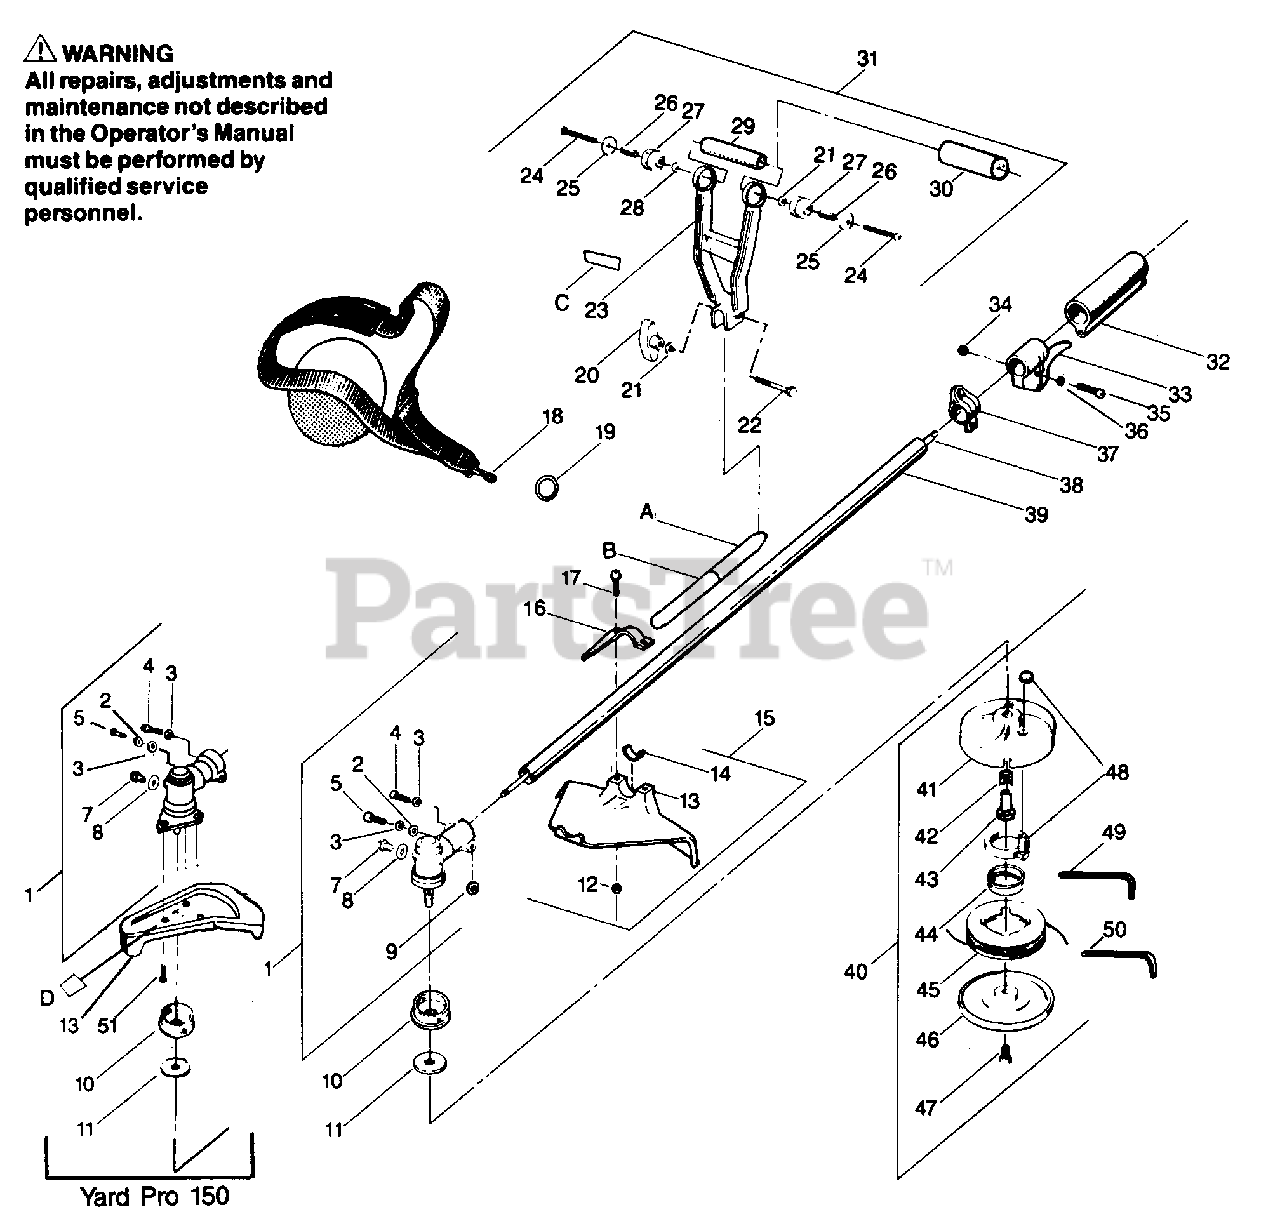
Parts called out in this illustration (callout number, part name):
2	Washer - 5mm - Flat - Gear Box - Index/Pinch Clamp
3	Lockwasher - 5mm - Gear Box - Index/Pinch Clamp
4	Screw - 5 x 12.5mm - Soc. Hd. - Gear Box - Index
5	Screw - 5 x 25mm - Soc. Hd. - Gear Box - Pinch Clamp
9	Washer - Spacer - Gear Box - Pinch Clamp - PRO150
10	Adaptor - Upper
11	Adaptor - Lower
12	Nut - 5mm - Shield - PRO150 Only
14	Spacer - Shield - PRO150 Only
15	Shield Ass'y.(incl.#12, 13, 14, 16 & 17) PRO150 Only
16	Bracket Shield - PRO150 Only
17	Screw - 5 x 25mm - Shield PRO150 Only
18	Shoulder Strap
19	Key Ring - Shoulder Strap
20	Knob - Handle
21	Washer - Handle
22	Screw - Handle - #1/4 - 20 x 1-3/4"
23	Handle Antivibe
24	Screw - #12 - 11 x 2" - Isolator Handle
25	Cup - Isolator - Handle
26	Spacer - Isolator Handle
27	Isolator - Handle
29	Center - Section - Handle
30	Cushion - Handle
31	Ass'y. - Antivibe Handle (Inc.23-30)
32	Grip - Drive Shaft Hsg.
33	Throttle Control Ass'y.
34	Lock Nut - Hex - 5mm - Throttle Control
35	Screw - 5 x 25mm Phil.
36	Washer - Throttle Control
37	Clamp - Shoulder Strap
40	Cutting Head Assembly (Inc.41-49)
41	Hub - Cutting Head
42	Line Saver - Cutting Head
43	Drive Adaptor - Cutting Head
43	Spring - Cutting Head
45	Spool w/Line - Cutting Head
46	Cover - Cutting Head
47	Screw - #3/8 - 16 x 7/8" - Cover
48	Release Button (Incl. Lock Ring)
49	Allen Wrench - Cutting Head
50	Hex Wrench - 4mm
51	Screw - YP150 Only
A	Decal - Safety Label (Upper)
B	Decal - Safety Label (Lower)
C	Decal - Antivibe
D	Decal - Warning Shield YP150
